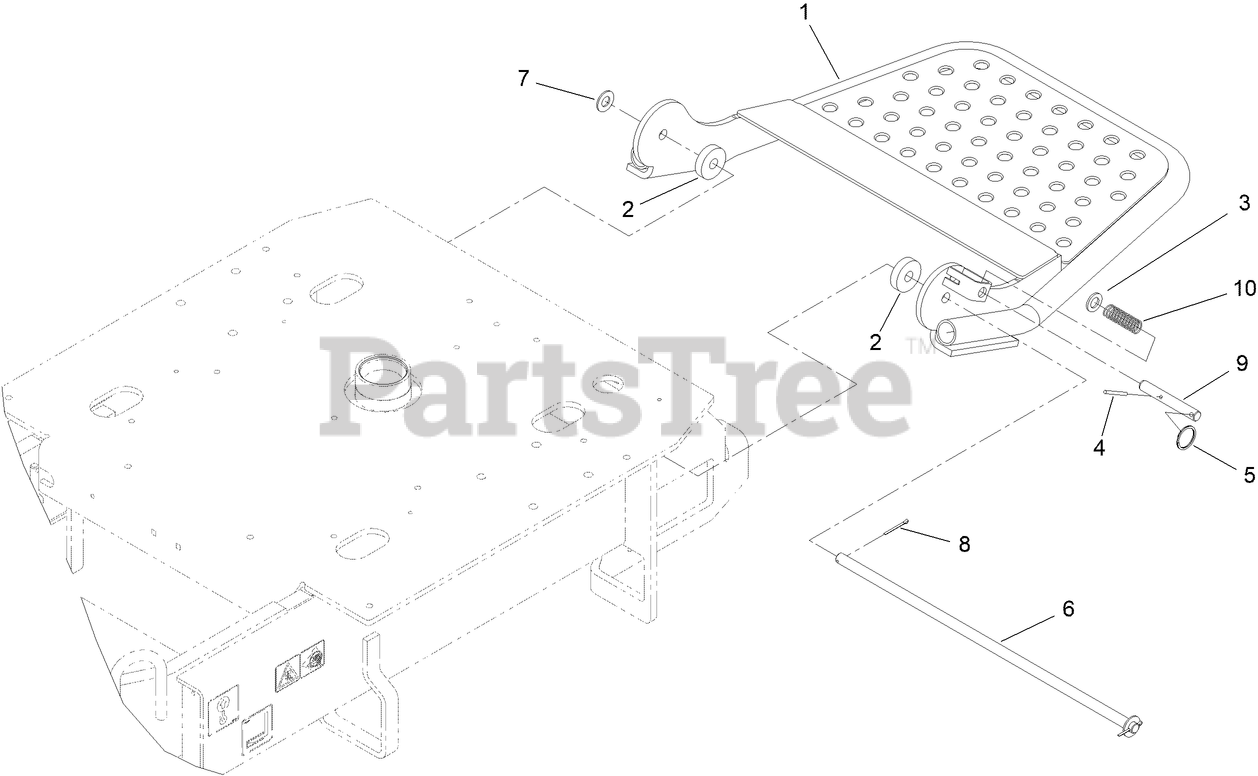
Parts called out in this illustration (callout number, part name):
1	STEP-PLATFORM-WELDED
2	SPACER
3	WASHER-FLAT
5	RING-SPLIT
6	SHAFT-PIVOT, STEP
7	WASHER-FLAT
8	PIN-COTTER
9	PIN-LOCKOUT, STEP
10	SPRING-COMPRESSION
